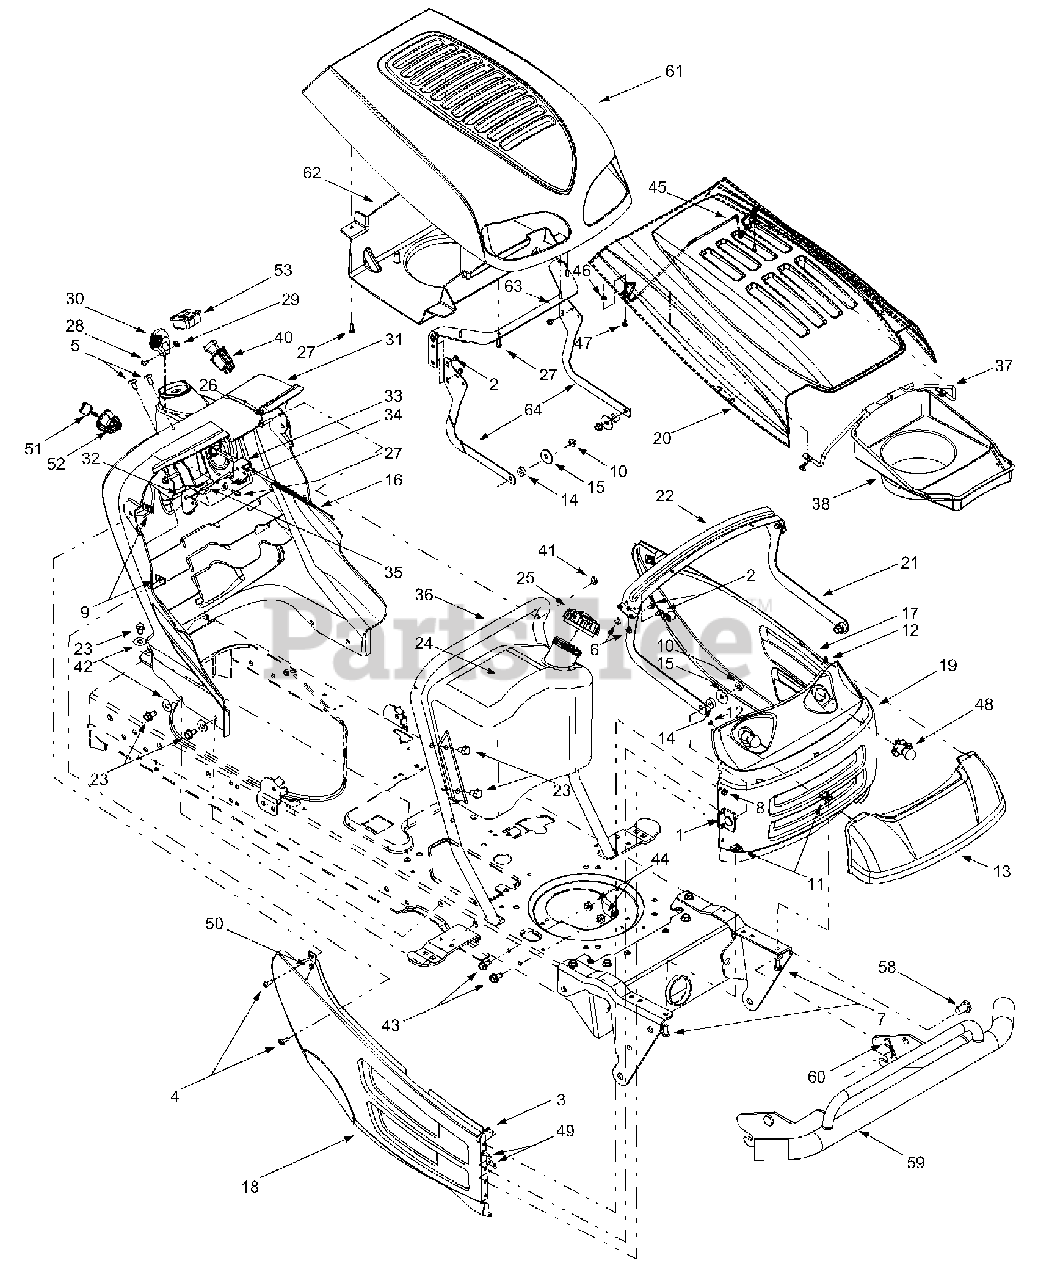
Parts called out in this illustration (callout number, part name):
2	Self-tapping Screw, 1/4-20 x .5
3	Hex Cap Screw, 1/4-20 x .62
4	Phillips Pan Screw, 1/4-20 x .75
5	Truss Phillips Screw, 1/4-20 x .625
6	Screw, #10-16 x .375
7	Hex Cap Screw, 5/16-18 x 1.0
8	Hex Sems Nut, 1/4-20
9	U-type Speed Nut, 1/4-20
10	Flange Lock Nut, 3/8-16
11	U-nut, 5/16-18
12	Retainer Nut, 3/8
13	Headlight Lens (8-style)
14	Rubber Washer, .87 x .33
15	Flat Washer, .406 x 1.5 x 11GA
16	Choke Knob/Cable
24	Fuel Tank, Three Gallon
25	Fuel Cap (Fits Either Tank)
26	Self-tapping Screw, 1/4-20 x 1.25
27	Self-tapping Screw, 1/4-15 x .75
28	Truss Phillips Screw, #8-32 x .375
29	Hex Nut, #8-32
30	Throttle Control Knob
31	Dash Panel
32	Cruise Control Button
33	Parking Brake Button
34	Flat Washer, 9/32 x 1/2 x 1/16
35	Brake/Cruise Pivot Rod
38	Hood Plenum
40	Electric PTO Switch
41	Hex Flange Lock Nut, 1/4-20
42	Flat Washer, .349 x 1.0 x .063
43	Screw, 5/16-18 x .875 (Grade 5)
44	Hex Nut, 5/16-18
45	Hood Latch
46	Hex Sems Nut, #10-32
47	Machine Screw, #10-24
48	Headlight Assembly
49	Hex Index Washer Screw, 1/4-14 x .0625
50	Rubber Bumper
51	Ignition Key w/ plastic cover
52	Ignition Switch
53	Systems Indicator Monitor w/ Hour Meter
58	Clevis Pin, .50 x .78
59	Bumper Assembly
60	Internal Cotter Pin
61	Hood, Red (7-Style)
62	Hood Plenum
